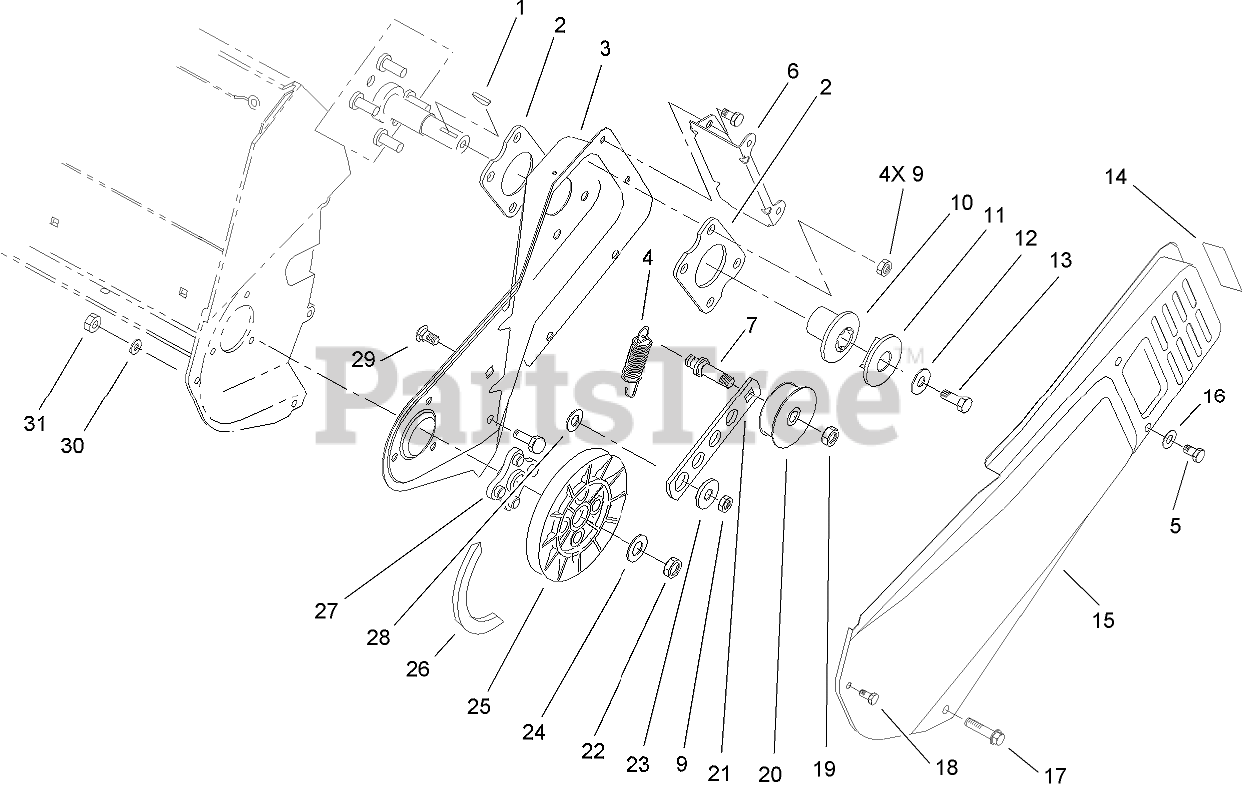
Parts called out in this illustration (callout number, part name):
1	KEY-WOODRUFF
2	PLATE-ENGINE
3	SIDEPLATE-LH
4	SPRING-EXTENSION
5	SCREW-HWH
6	BRACKET-COVER, BELT
7	PIN-IDLER
9	NUT-LOCK, NI
10	Hub-HALF SHEAVE
11	CAP-HALF SHEAVE
12	WASHER-FLAT
13	SCREW-HH
14	DECAL-WARNING
15	COVER-BELT
16	WASHER-FLAT
17	SCREW-PLASTIC
19	NUT-LOCK, NI
20	PULLEY-IDLER
21	ARM-IDLER
22	NUT-LOCK, NI
23	BUSHING-IDLER
24	WASHER-FLAT
25	PULLEY-DRIVEN
26	V-BELT
28	WASHER
29	SCREW-CARR
30	WASHER-FLAT
31	NUT-LOCK, NI
